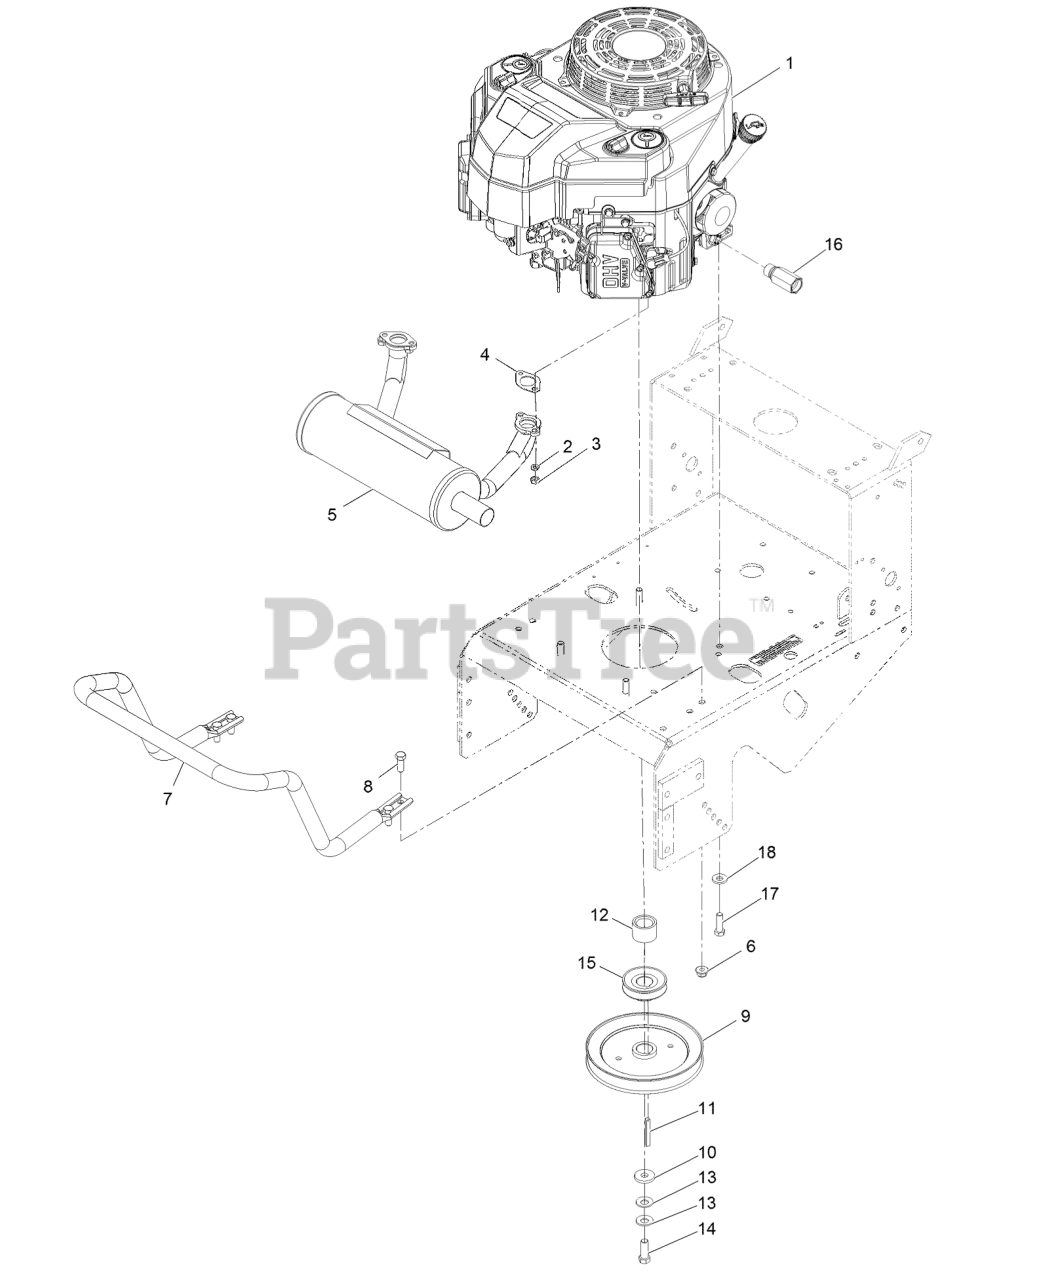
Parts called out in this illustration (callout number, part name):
1	Engine-Kawasaki
2	WASHER-LOCK
4	GASKET-EXHAUST
5	MUFFLER-HORIZONTAL, OFFSE
6	NUT-HF, NI
7	GUARD-MUFFLER
8	SCREW-HH
12	SPACER-CLUTCH
13	WASHER-SPRING
14	SCREW-HH
15	SHEAVE-TRANSMISSION
16	ADAPTER
17	SCREW-HH
18	WASHER-BELLEVILLE
